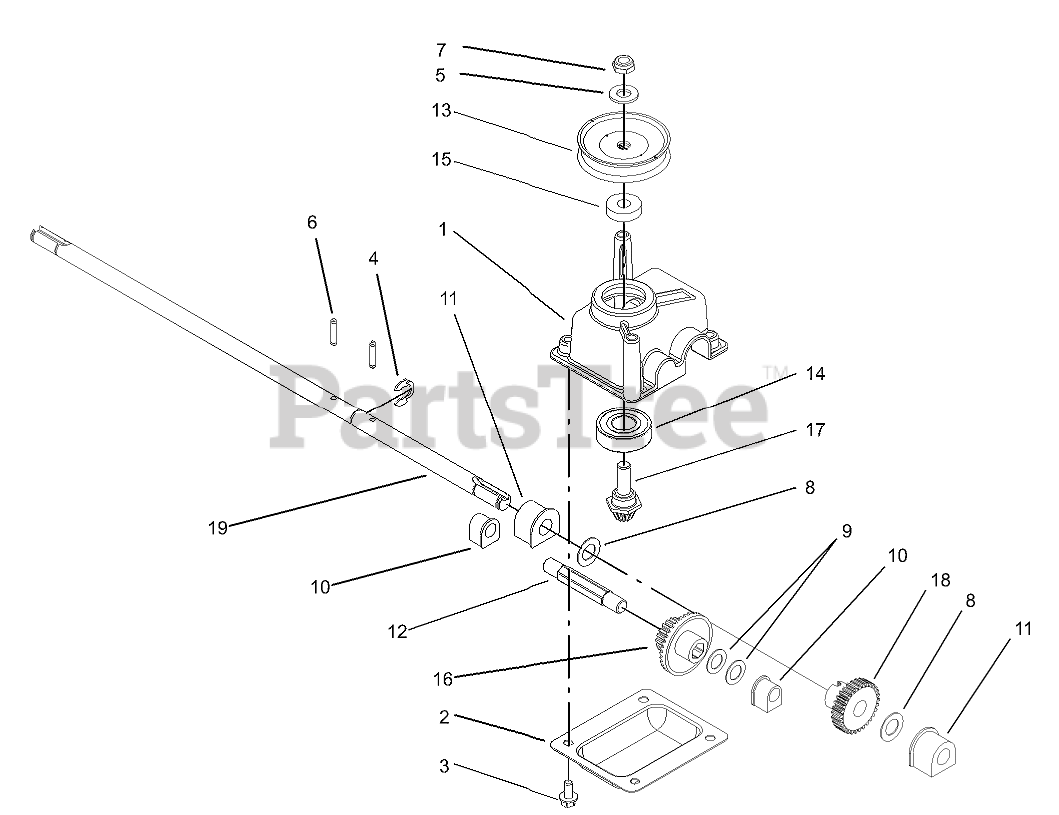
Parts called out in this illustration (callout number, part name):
1	CASE-GEAR
2	COVER-CASE, GEAR
3	SCREW-HWH
4	RING-RETAINING
5	WASHER-FLAT
6	PIN-GROOVE
7	NUT-HEX
8	WASHER-PLAIN
9	WASHER-THRUST
10	BUSHING
11	BUSHING
12	SHAFT-INTERMEDIATE
13	PULLEY-HALF
14	BEARING-BALL
15	SPACER
16	GEAR-19T SPUR, 37T BEVEL
17	GEAR-PINION, BEVEL
18	GEAR-30T
19	SHAFT-OUTPUT
